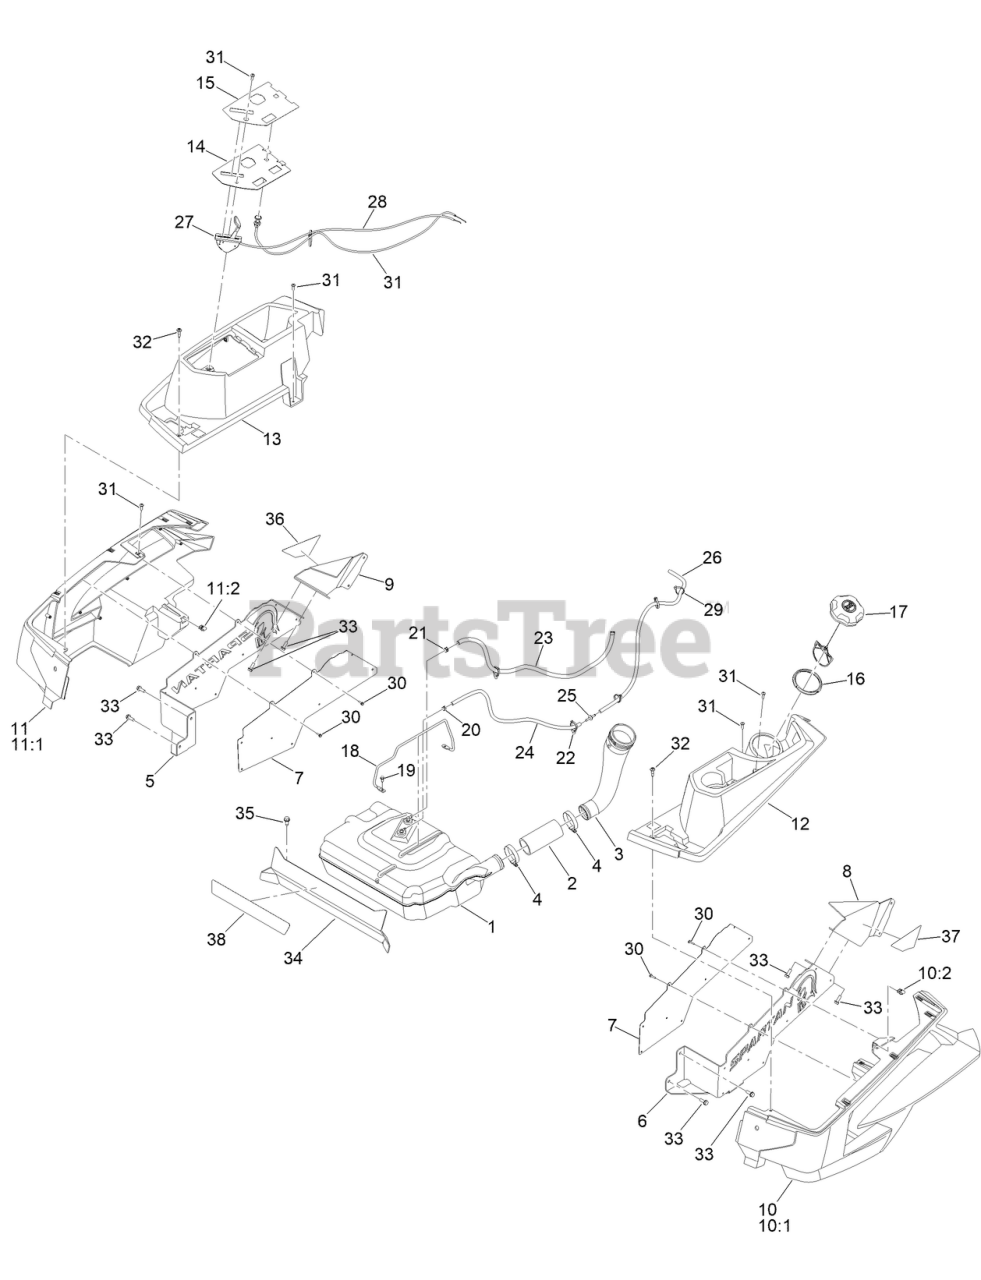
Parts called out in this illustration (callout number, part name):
1	TANK-FUEL, ASM
2	HOSE-FILLER, FUEL
3	NECK-FILLER, FUEL
4	CLAMP-HOSE
5	BRACKET-MOUNT, RH POD
6	BRACKET-MOUNT, LH POD
7	PLATE-BACK
8	BRACKET-MOUNT, LH POD
9	BRACKET-MOUNT, RH POD
10	LH LOWER POD ASM
10:1	POD - LOWER LH
11	RH LOWER POD ASM
11:1	POD - LOWER RH
12	LH UPPER POD W/DECAL ASM
13	RH UPPER POD W/DECAL ASM
14	PLATE-CONTROL
15	DECAL-CONTROL PANEL
16	RING-RETAINING
17	CAP-FUEL, RATCHETING
18	ROD-HOLD DOWN
19	SCREW-HWH
20	CLAMP-HOSE
21	CLAMP-HOSE
22	CLIP-TIE
23	HOSE-FUEL
24	HOSE-FUEL
25	ADAPTER ORIFICE
26	HOSE-LP
27	CABLE-THROTTLE
28	CABLE-CHOKE
29	TIE-CABLE
30	SCREW-PLASTITE, HWH
31	SCREW-PH
32	SCREW-TORX
33	SCREW-TAPTITE
34	PLATE-KICK
35	SCREW-HWHTF
36	DECAL-DEFENDER, RH
37	DECAL-DEFENDER, LH
38	DECAL-DEFENDER, FRONT
